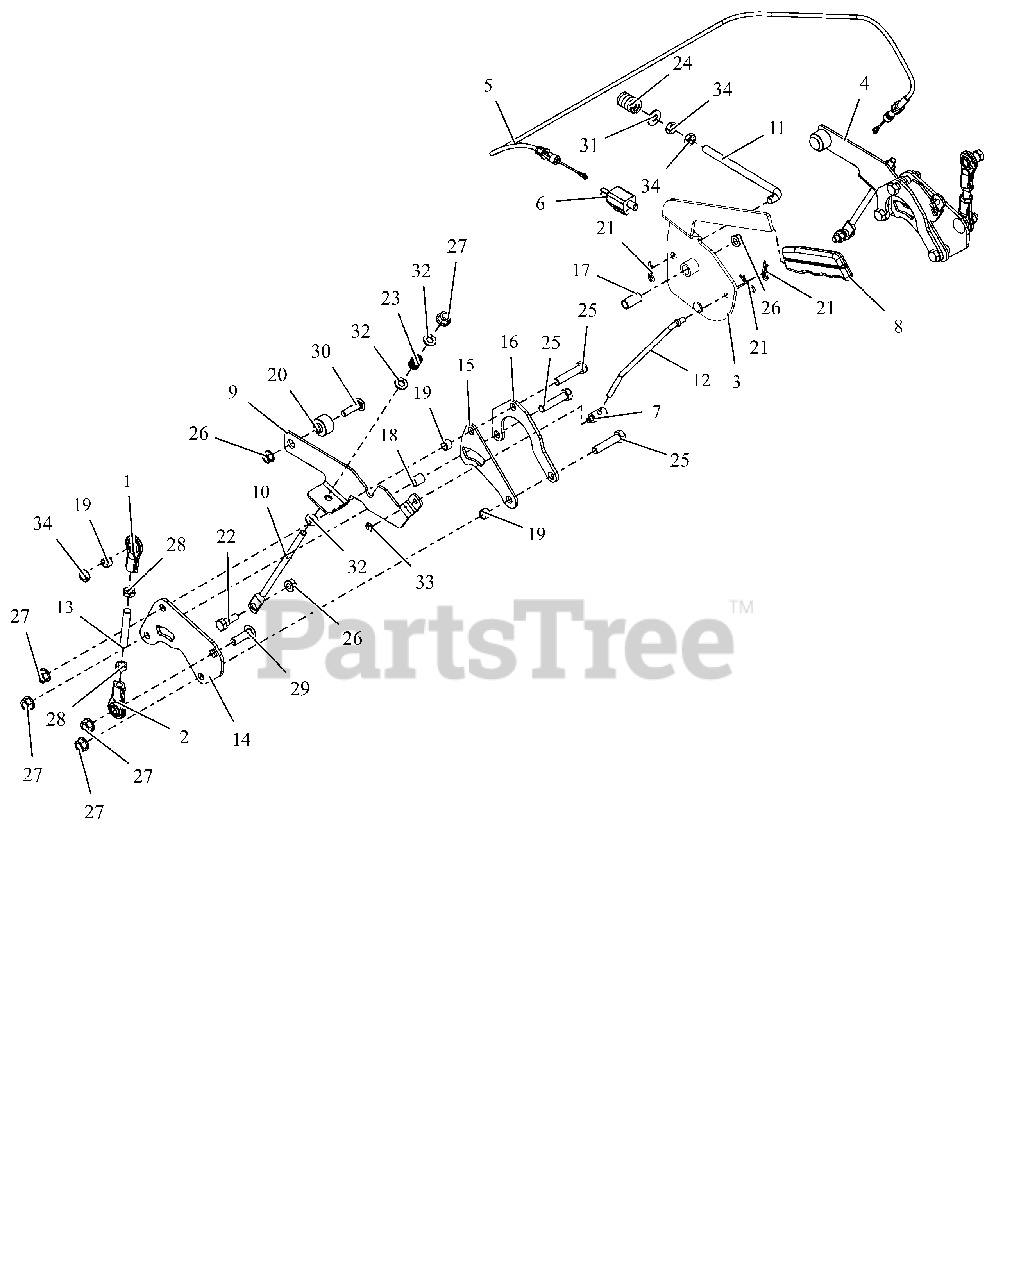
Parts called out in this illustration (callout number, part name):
1	ROD END, .38 RH
2	END, ROD-.38 LH
3	LEVER, PARKING BRAKE
4	ARM, BRAKE - LH (W/PIN)
5	CABLE, BRAKE
6	SWITCH, SINGLE POLE N.O.
7	TRUNION, 1/4-20
8	GRIP, PARKING BRAKE (YELLOW)
9	ARM, BRAKE-RH
10	ROD, LINK - TRANSMISSION BRAKE
11	ROD, OVER CENTER
12	ROD, BRAKE LINK
13	ROD, STEERING LINK
14	BRKT, TRANSAXLE STEERING
15	BRKT-SPACER
16	PLATE, REAR REINFORCING
17	BSHG-SLV .385X.500X1.045
18	SPCR, SLV .385X.500X.652
19	SPCR, SLV .385X.500X.350
20	SPCR, FLANGE
21	PIN, HAIR #213 .08X1.19 ZCC
22	BOLT,SHLDR .38X.25 -.31-18X.75
23	SPRING, COMPRESSION
24	SG-COMP .187X.56X1.62
25	BLT, HEX .38-16X1.75 G5 ZCC
26	NUT-LK-TOP-FLG .312-18 GF ZCC
27	NUT-LK-TOP-FLG .38-16 ZC120
28	NUT, HEX-JAM .38-24 ZCC
29	BLT,RHSSN .38-16X1.25 G5 ZCC
30	BTL,RHSSN .313-18 X 1.25 G5 ZCC
31	WSHR,FLT .375X.875X.083 ZCC
32	WSHR,FLT .344X.688X.065 ZCC
33	RG-RTNG-EXT .250X.025
34	NUT-JAM .375-16 G2 ZCC
